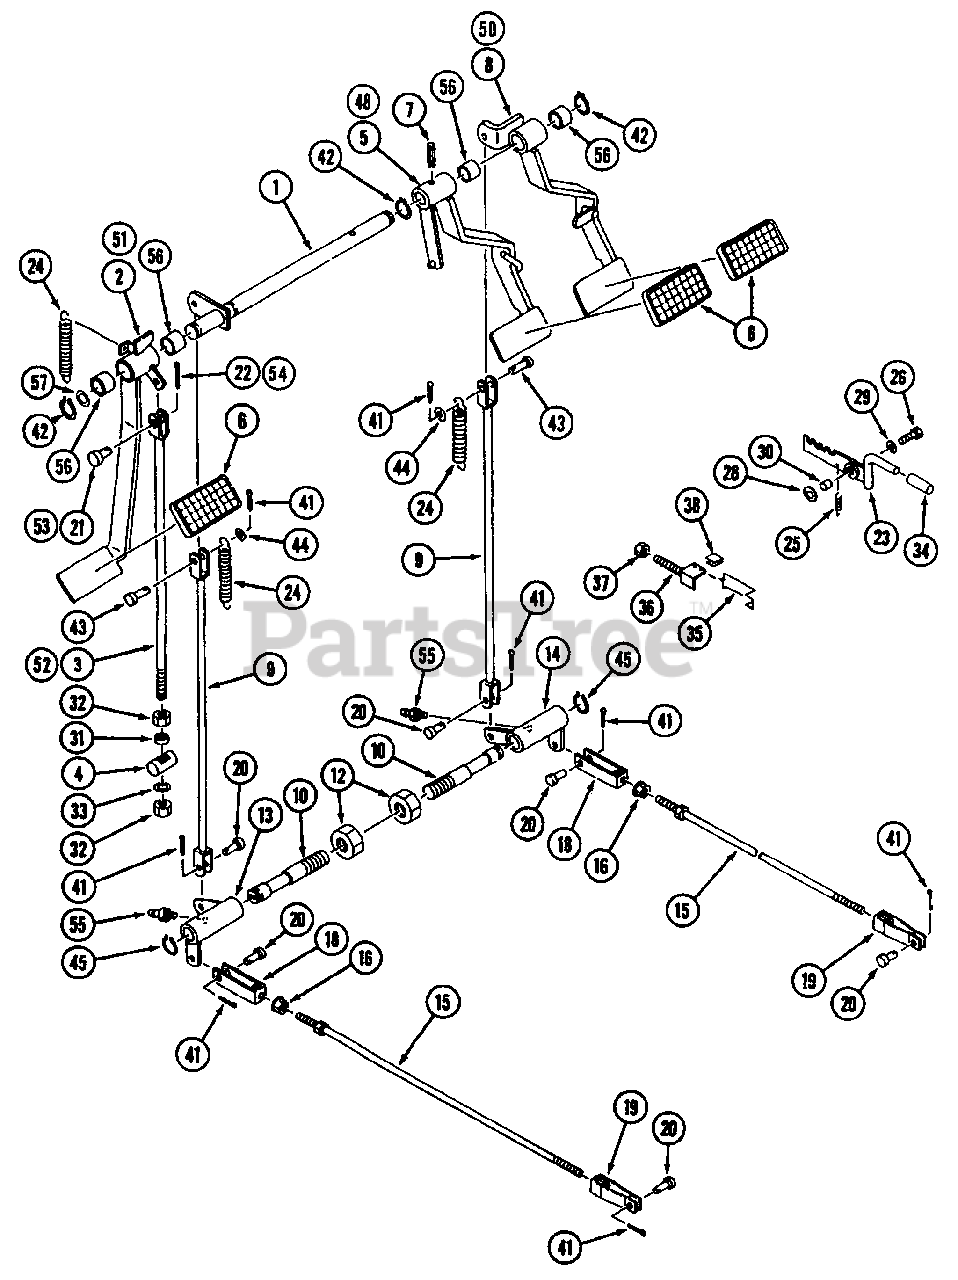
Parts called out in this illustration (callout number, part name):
2	Pedal, Clutch (HST)
3	Rod, Clutch (HST)
5	Pedal, Brake L.H. (Gear)
8	Pedal, Brake R.H. (Gear)
13	Link, Brake L.H.
14	Link, Brake R.H.
21	Pin, Clevis (HST)
22	Pin, Split (HST)
23	Lever, Parking Spring
35	Hook, Clutch Pedal
36	Bolt, Stopper
48	Pedal, Brake L.H. (HST)
50	Pedal, Brake R.H. (HST)
51	Pedal, Clutch (Gear)
52	Rod, Clutch (Gear)
53	Pin, Clevis (Gear)
54	Pin, Split (Gear)
55	Grease, Nipple
